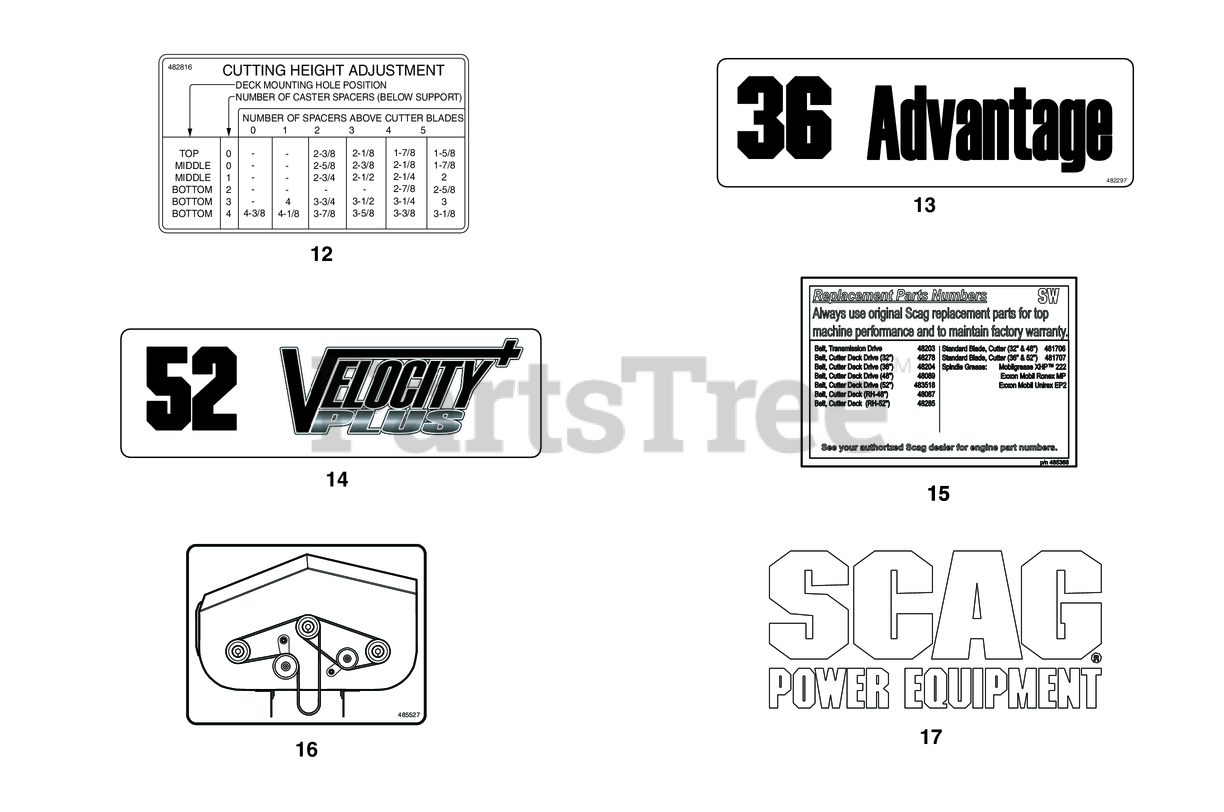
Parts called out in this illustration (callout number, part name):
12	DECAL, HEIGHT OF CUT - SWM
13	Decal, 32
15	Decal, SW Replacement Parts
16	Decal, Belt Routing - 32 & 36A
17	Decal, Scag Power Equipment (Fuel Tank)
